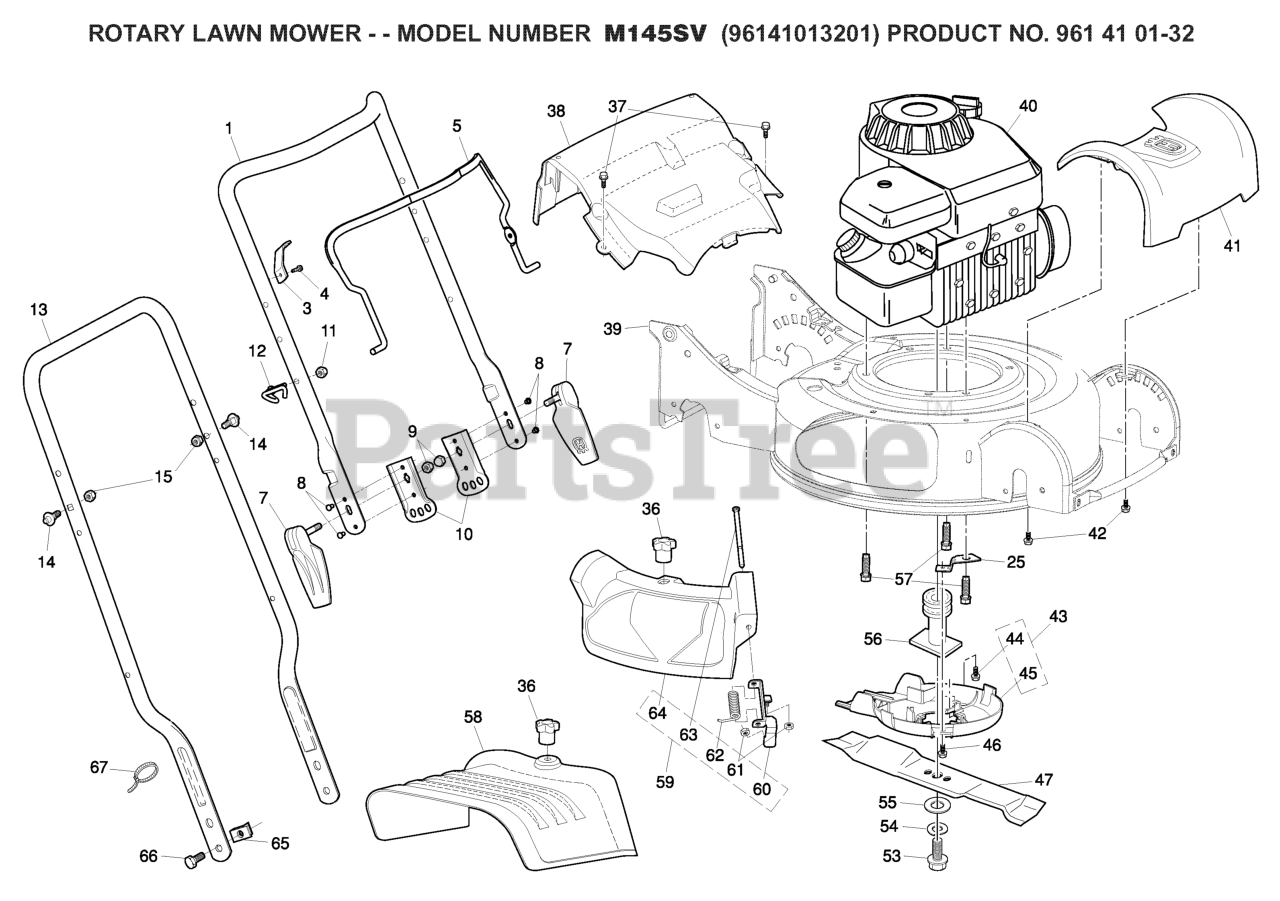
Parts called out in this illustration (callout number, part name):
1	HANDLE.ASM.UP.W/ADJ.BKT
3	BRACKET
5	BAIL CONTROL
7	ASM.QUICK.RELEASE
9	Locknut, Hex 1/4-20
10	BRACKET.ADJ.3POS.GREY
11	NUT
12	RB GUIDE.ROPE.STD.BLK.ZIN WSL
14	STUD.QUICK.ADJUST
15	NUT.LOCK.5/16-18
25	BRACKET
36	KNOB.MULCH.DOOR
37	SCREW, HEX WASHER HEAD
42	SCREW.HWH.13-16-5.8.BZP
44	HINGE SCREW
46	SCREW.HEX.WSH
53	BOLT.HD.HEAD.3/8-24X2.50 (2 2)
54	LOCKWASHER
55	WASHER,HARDEN
57	BOLT 3/8-16X1-1/8
61	NUT.HEX.FLANGE.1/4
62	SPRING.MULCH.DOOR
63	ROD.HINGE.1/4"3.82"
64	DOOR.MULCH.GREY
67	TIE GUIDE
